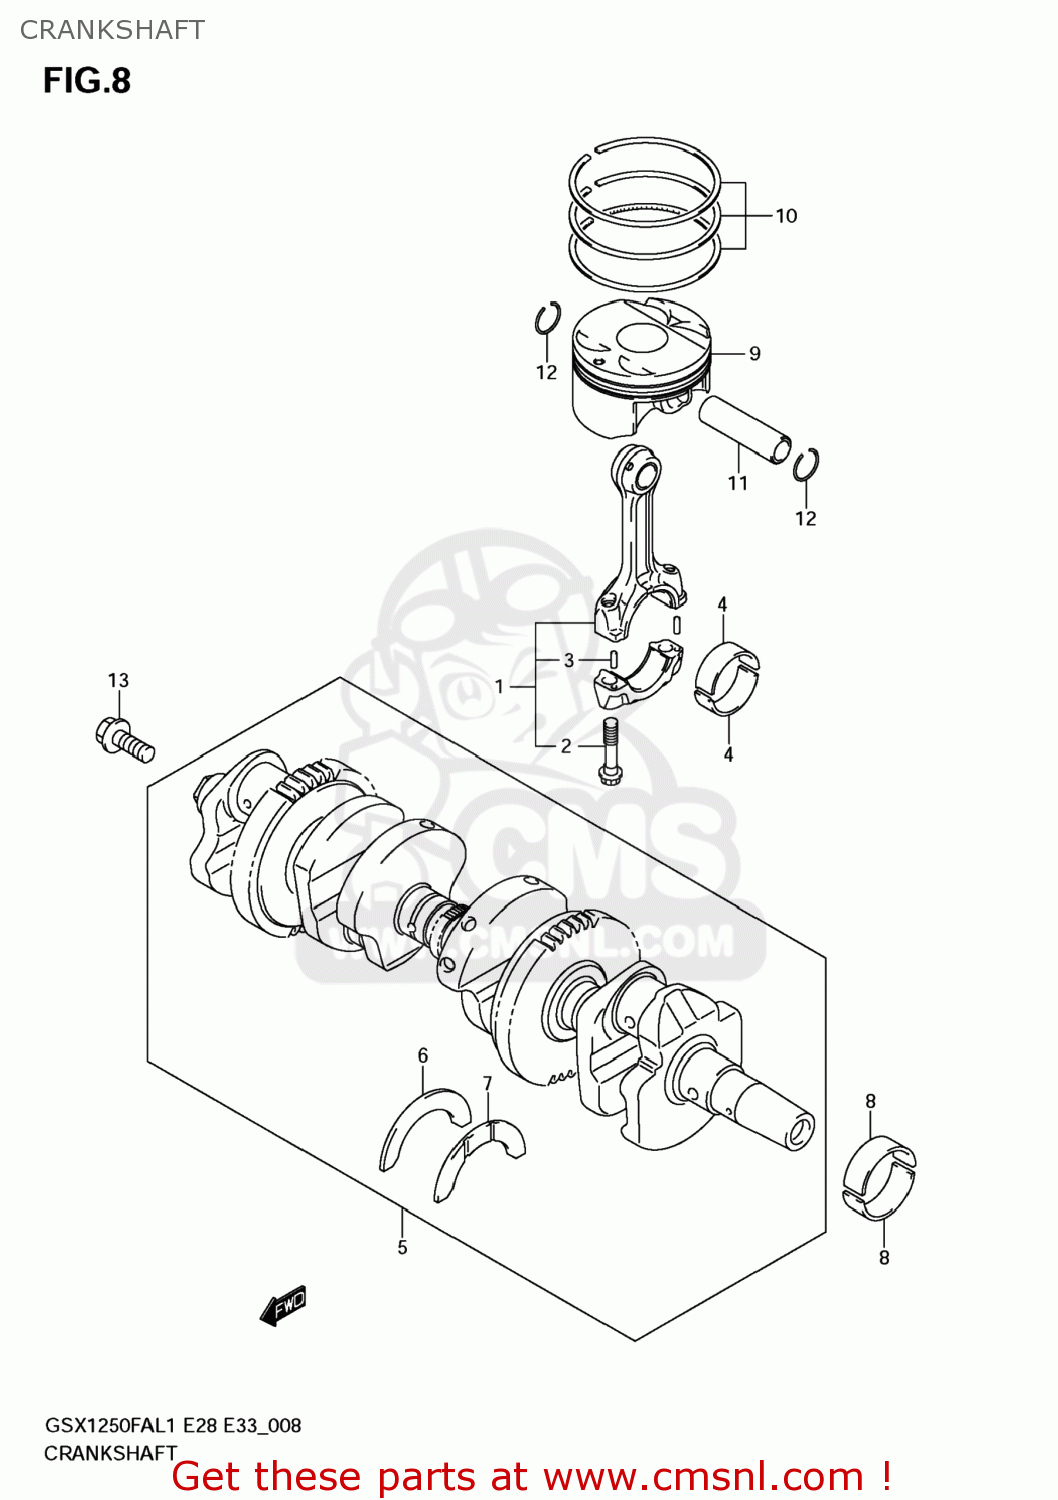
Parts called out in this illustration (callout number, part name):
1	CONNECTING ROD ASSY
2	BOLT,CONNECTING ROD
3	PIN
4	BEARING,CRANK PIN
5	CRANKSHAFT SET
6	BEARING,CRANK THRUST(GREEN)
7	BEARING,CRANK THRUST(RED)
8	BEARING,CRANKSHAFT
9	PISTON
10	RING SET,PISTON
11	PIN,PISTON
12	CIRCLIP
13	BOLT
